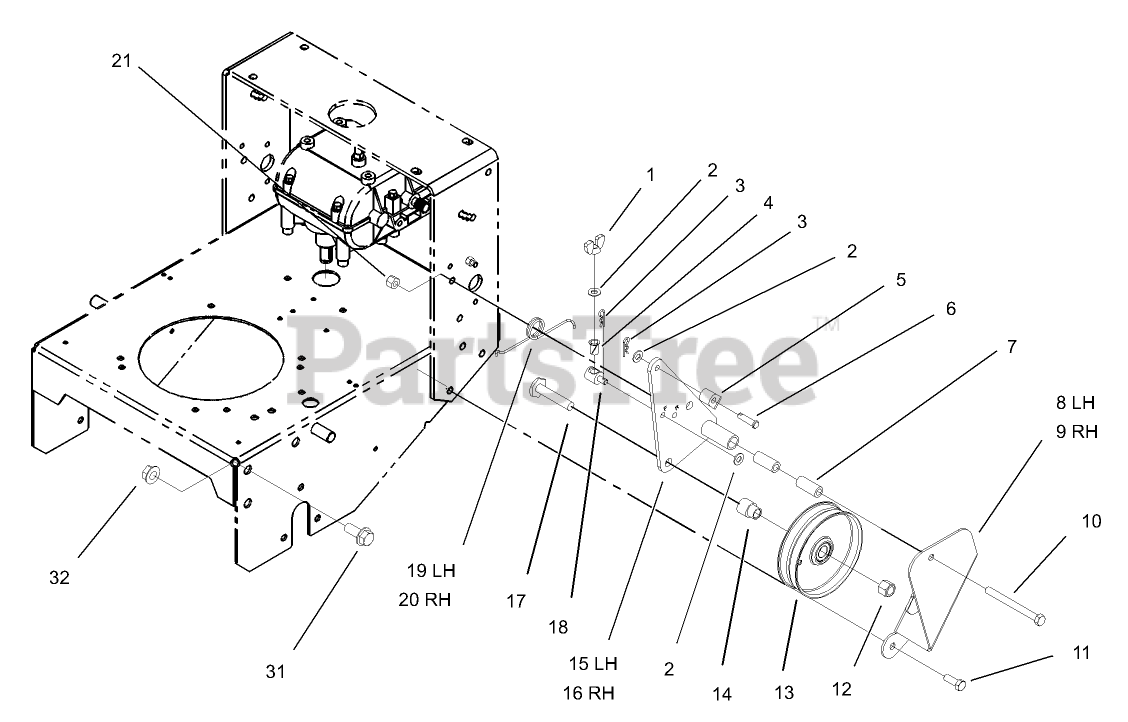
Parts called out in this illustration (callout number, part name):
1	NUT-WING
2	WASHER-PLAIN
3	PIN-COTTER
4	BUSHING-NYLON
5	FITTING-ROD
6	PIN-CLEVIS
7	SPACER-PIVOT, IDLER
8	BRACKET-SUPPORT, LH
9	BRACKET-SUPPORT, RH
10	SCREW-HH
11	SCREW-HH
12	NUT-LOCK, NI
13	PULLEY-IDLER
14	SPACER-PULLEY
15	BRACKET-IDLER, LH
16	BRACKET-IDLER, RH
17	SCREW-LEVELER
18	FITTING-ROD
19	SPRING-TORSION, LH
20	SPRING-TORSION, RH
21	NUT-LOCK, NI
31	SCREW-HHF
32	NUT-HF
